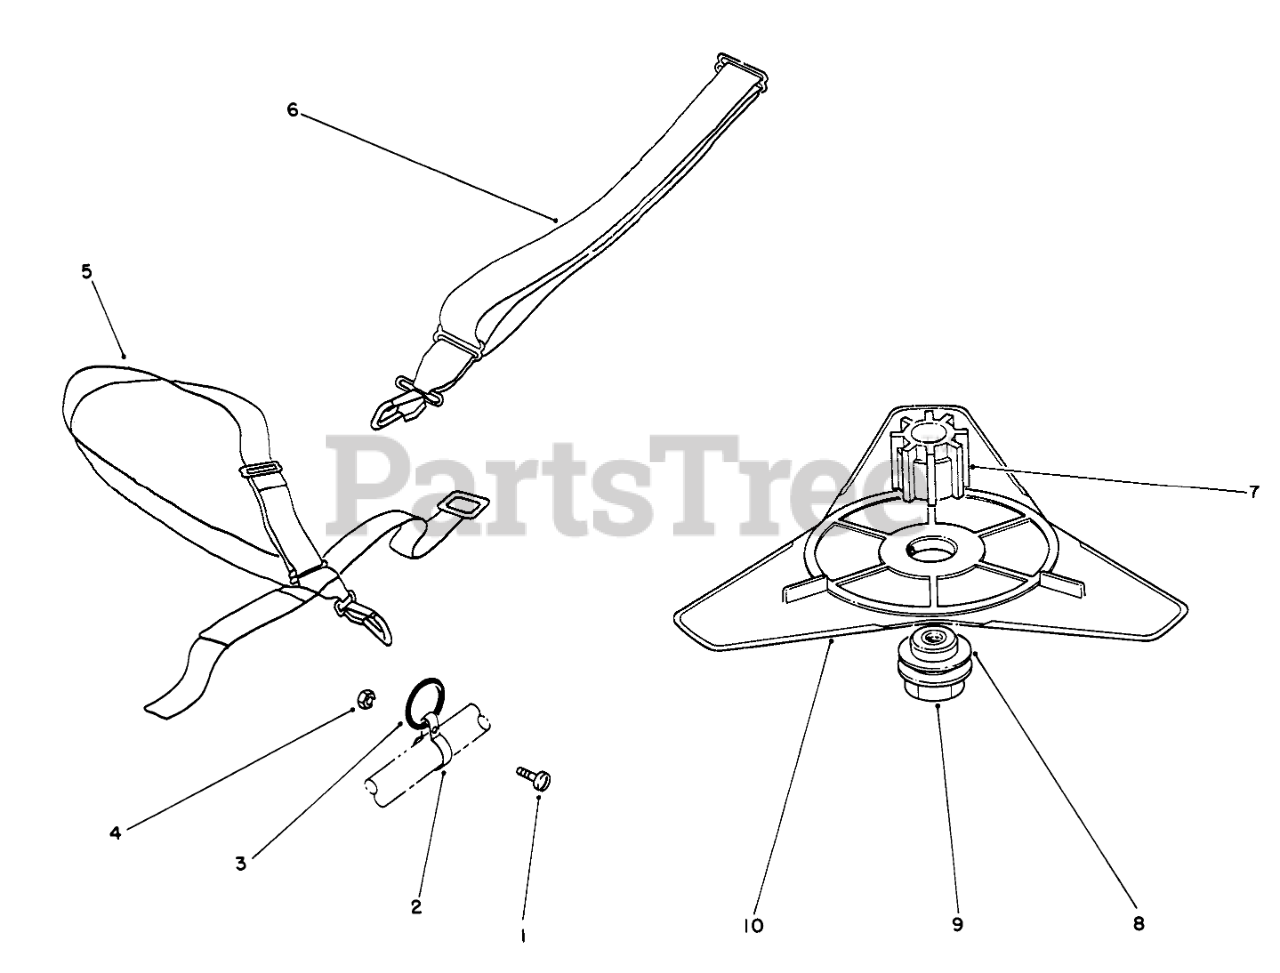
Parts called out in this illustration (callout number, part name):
1	SCREW-SRH
2	HARNESS CLAMP
3	RING-HARNESS
4	NUT-LOCK, NI
5	Deluxe Harness
6	Harness
7	BLADE ADAPTER
8	FLAT WASHER
9	ADAPTER NUT
10	FLEX BLADE PKG
